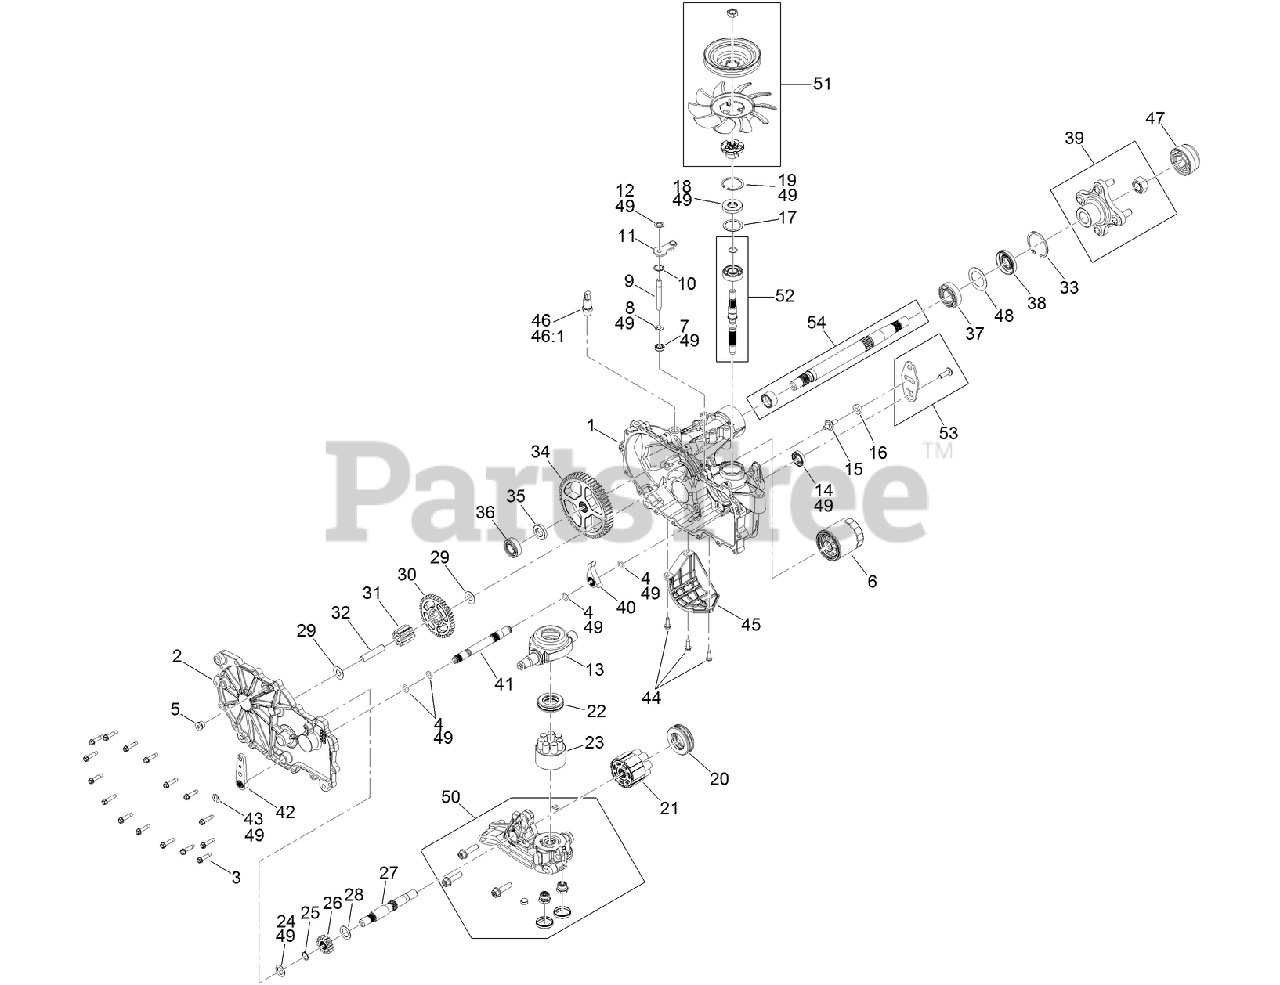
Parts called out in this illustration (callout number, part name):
1	MAIN HOUSING KIT
2	LH SIDE COVER KIT
3	SCREW-HHF
4	O-RING
5	PLUG-THREAD, STRAIGHT
6	ELEMENT-OIL FILTER, HYD
7	SEAL-LIP
8	RING-RETAINING, EXTERNAL
9	ROD-BYPASS
10	RING-RETAINING, INTERNAL
11	ARM-BYPASS
12	RING-RETAINING, EXTERNAL
13	SWASHPLATE-TRUNNION
14	SEAL-LIP
16	PUCK-FRICTION
17	SPACER
18	SEAL-LIP
19	RING-RETAINING
20	BEARING-THRUST
21	MOTOR CYLINDER BLOCK KIT
22	BEARING-THRUST
23	PUMP BLOCK ASM
24	WASHER-FLAT
25	RING-RETAINING
26	GEAR-16T
27	SHAFT-MOTOR
28	WASHER
29	WASHER
30	GEAR-43T
31	GEAR-11T
32	PIN-JACKSHAFT
33	RING-RETAINING
34	GEAR-54T
35	SPACER
36	BEARING-BALL
37	BEARING-BALL
39	HUB KIT
40	PAWL-BRAKE
41	SHAFT-BRAKE, INBOARD
42	HANDLE-BRAKE
43	RING-RETAINING, EXT
45	GUARD-FILTER, LH
46	ADAPTER-STRAIGHT
46:1	O-RING
47	COVER-NUT, AXLE
48	SPACER
49	SEAL KIT
50	CENTER SECTION KIT
51	FAN PULLEY KIT
52	INPUT SHAFT KIT
53	CONTROL ARM KIT
54	AXLE SHAFT KIT
